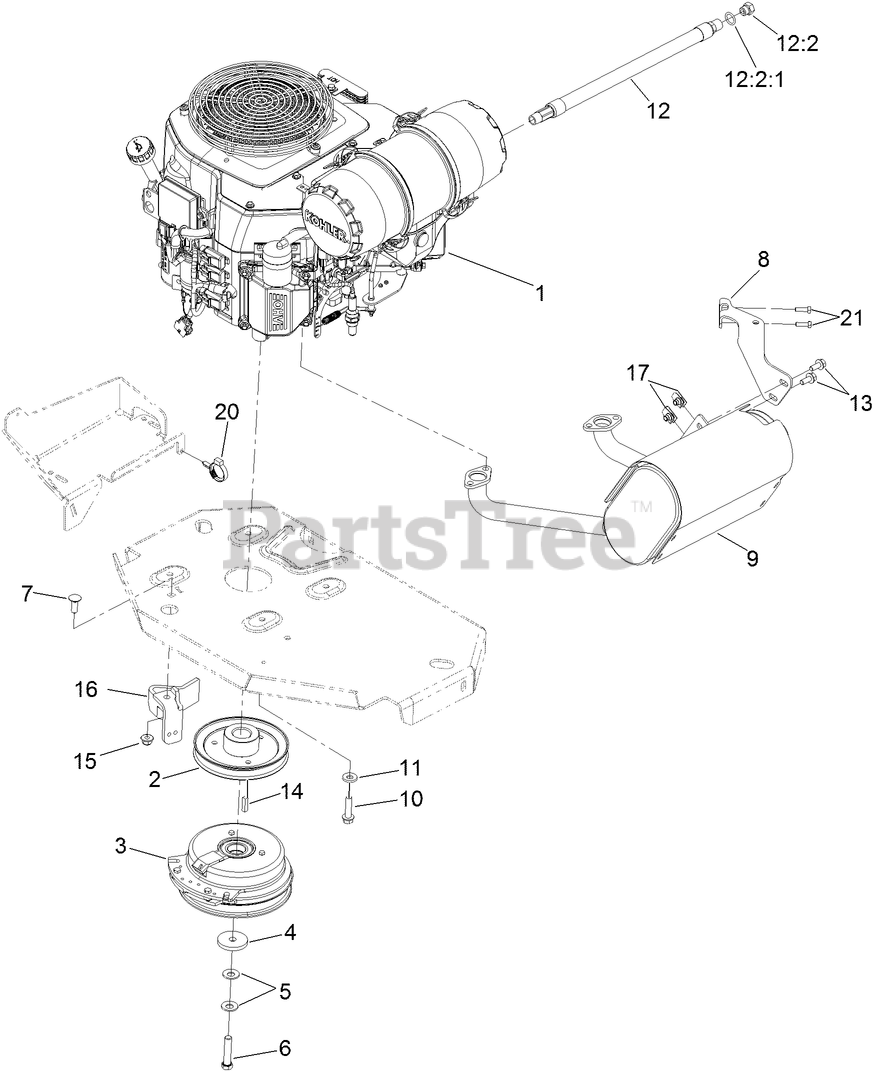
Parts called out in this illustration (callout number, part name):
1	ENGINE-KOHLER, PCV740 EFI LP
2	SHEAVE
3	CLUTCH KIT
4	WASHER-CLUTCH
5	WASHER-SPRING
6	SCREW-HH W/LOCTITE
7	SCREW-CARR
8	MUFFLER BRACKET KIT
9	MUFFLER
10	SCREW-HWH
11	WASHER-BELLEVILLE
12	OIL DRAIN HOSE ASM
12:2	PLUG-HH
12:2:1	O-RING
13	SCREW-HHF
15	NUT-HF, NI
16	CLUTCH-ANCHOR
17	NUT-U
20	CLAMP-HOSE
21	SCREW-HH
